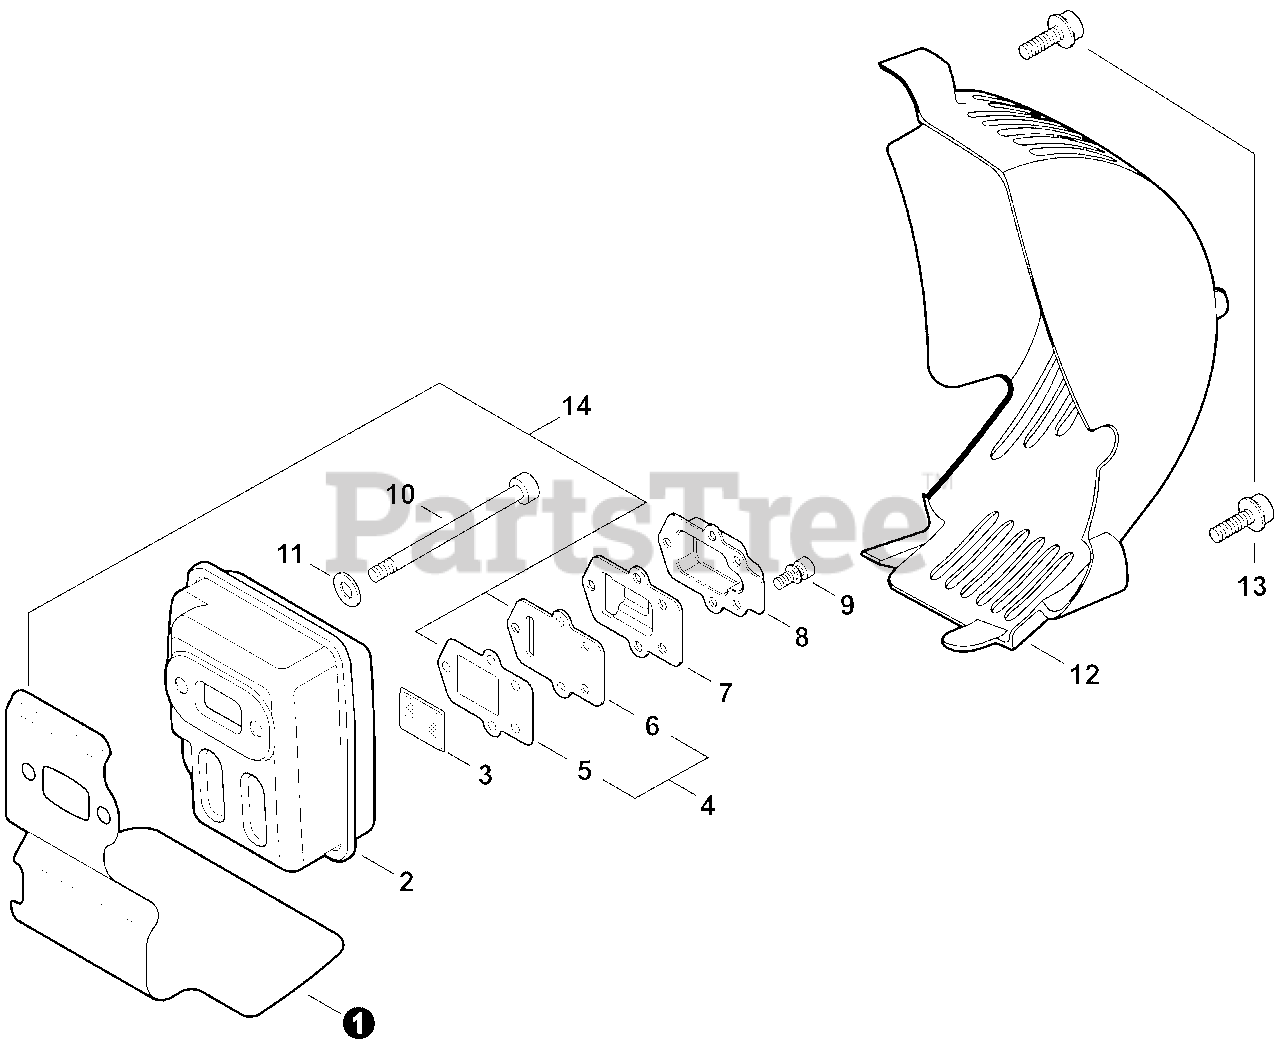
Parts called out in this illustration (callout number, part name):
1	HEAT SHIELD, EXHAUST
2	MUFFLER
3	SCREEN, SPARK ARRESTER
4	GASKET KIT, EXHAUST
5	GASKET, EXHAUST
6	GUIDE, EXHAUST
7	GUIDE, EXHAUST
8	GUIDE, EXHAUST
9	SCREW 4×10
11	WASHER 5.5×12×0.8
12	COVER, MUFFLER
13	BOLT 5×14
14	GASKET KIT
